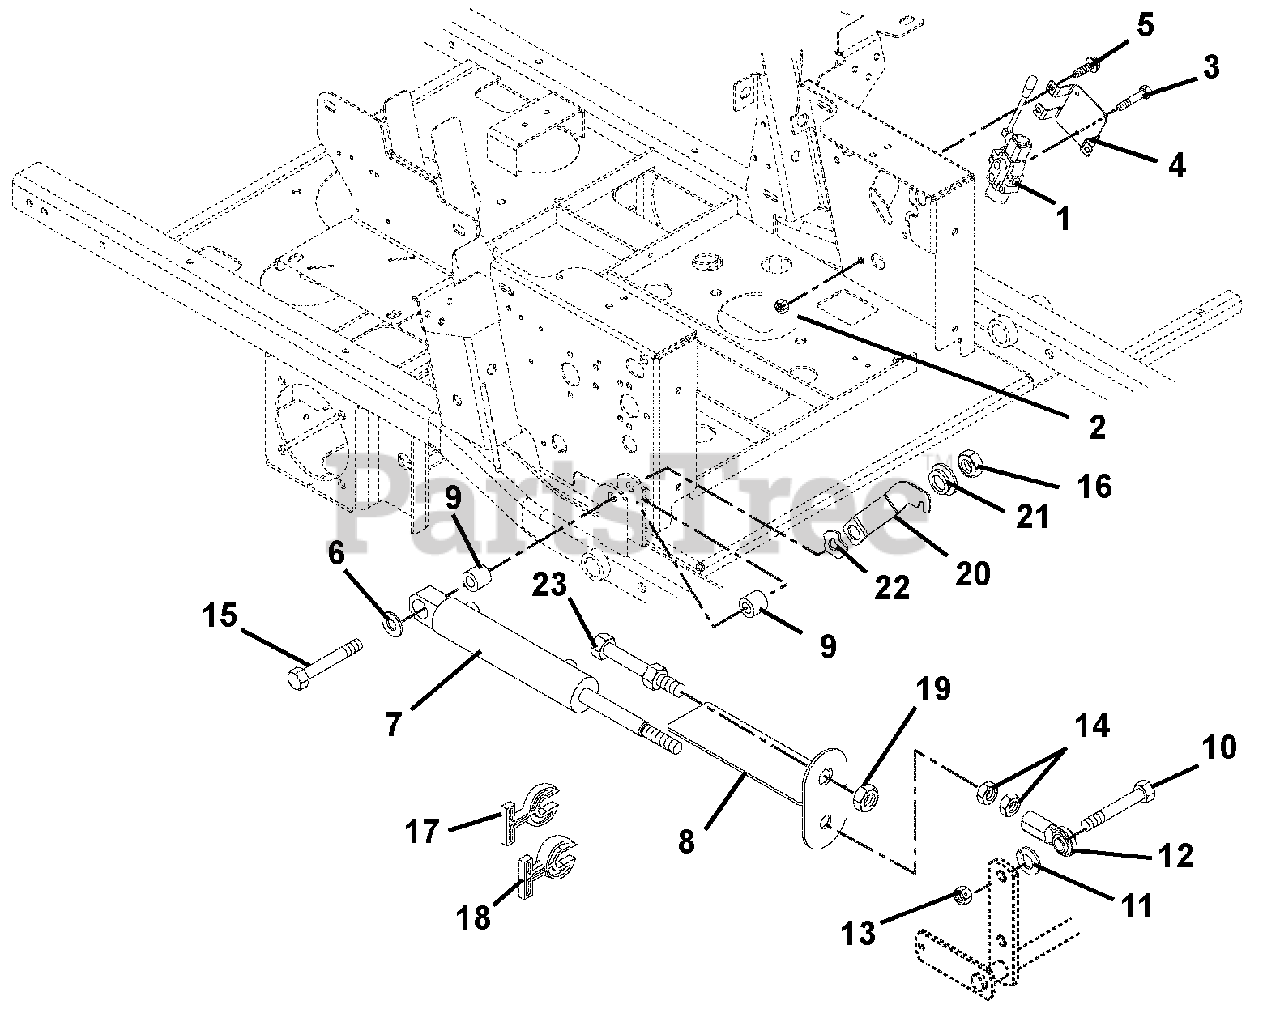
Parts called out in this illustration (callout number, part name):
1	Valve, Hydraulic
2	Nut, Locking Top Flange .31-18
3	Bolt, Hex .31-18 x 2.5 Grade 5
4	Bracket, Valve Mounting
5	Screw, Tapping .38-16 x .50 Hex Washer Head
6	Washer, Flat Steel .515 x 1.625 x .25
7	Cylinder, Hydraulic Lift
8	Strap, Cut Indicator / Guard
9	Bushing .516 x 1.00 x 1.05
10	Bolt, Hex .62-11 x 2.25 Grade 8
11	Washer, Lock .62 x .156
12	Rod End, Right Hand Female .625
13	Nut, Locking Center .62-11
14	Nut, Jam .625-18
15	Bolt, Hex .50-13 x 3.75 Grade 5
16	Nut, Locking Top Flange .50-13
17	Stop, Cylinder .34 Thick
18	Stop, Cylinder .68 Thick
19	Nut, Jam .75-16
20	Latch, Footboard
21	Bushing, Flange .515 x .75 x .275 x 1.12
22	Washer, Wave .076 x 1.12 x .08
